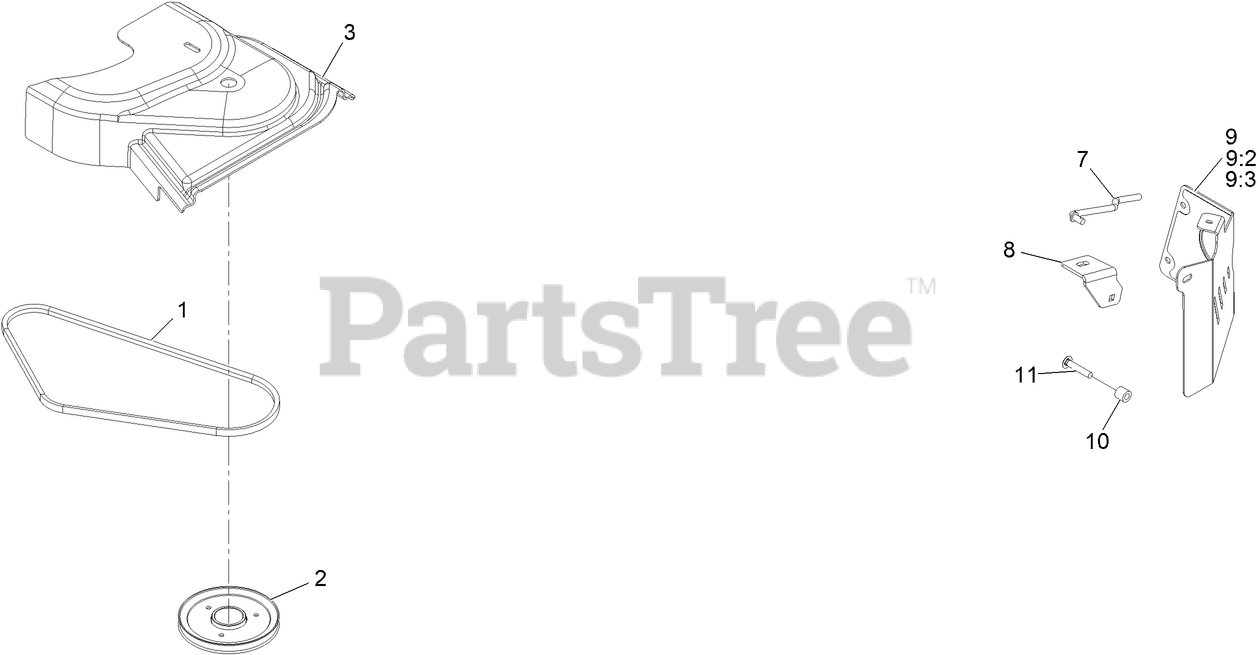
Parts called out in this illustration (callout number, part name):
2	SHEAVE,DRIVE LZUV 726
3	COVER,BELT UV 72
7	LINK-HANDLE
8	BRACKET-HANDLE MOUNT
9	PANEL ASM, BAGGER LH QUARTER
9:2	DECAL-WARNING
9:3	Shield-Bagger LH Quarter Panel
11	BOLT-CARRIAGE
